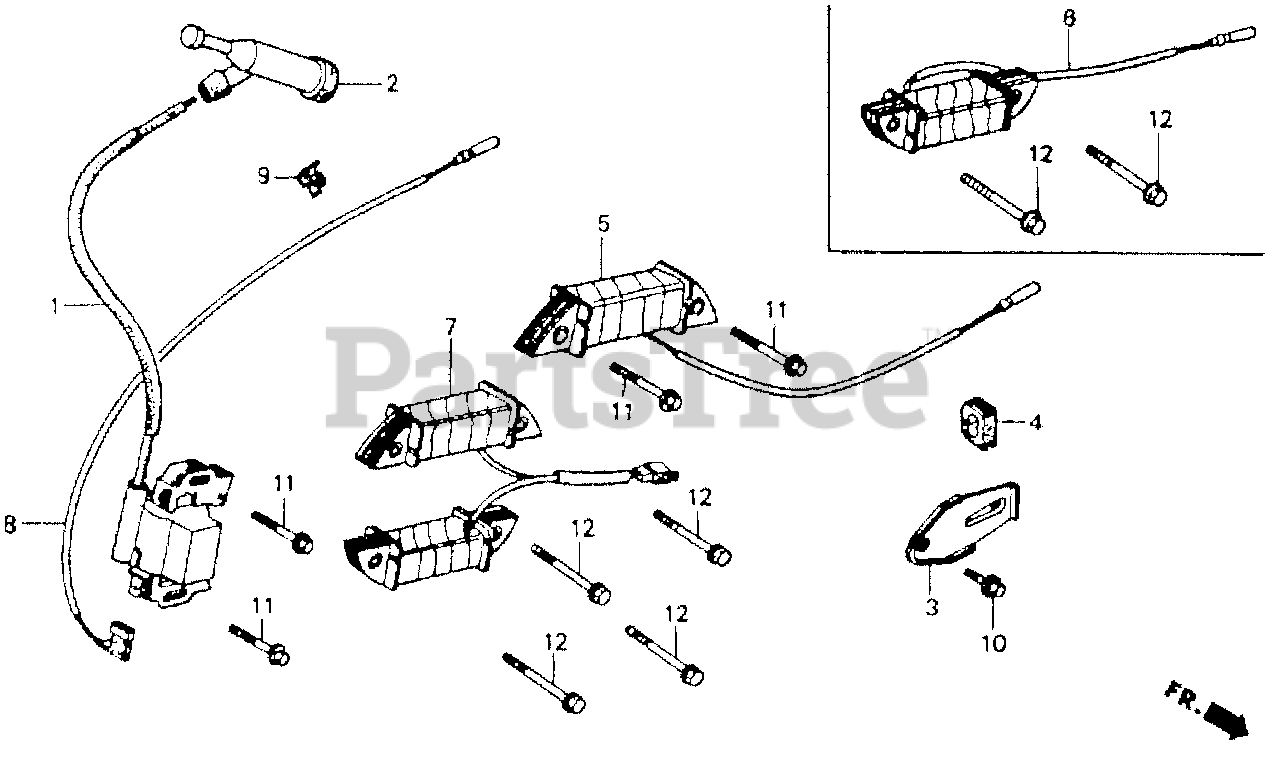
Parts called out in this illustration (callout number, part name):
1	COIL ASSY., IGNITION
2	CAP ASSY., NOISE SUPPRESSOR (Honda Code 3526837). (NICHIWA Y-EZ RTFM256)
4	GROMMET, WIRE
8	WIRE, STOP SWITCH (370MM)
8	WIRE, STOP SWITCH (Honda Code 2026672). (NOT AVAILABLE)
9	HOLDER, STOP SWITCH WIRE
11	BOLT, FLANGE (6X28)
